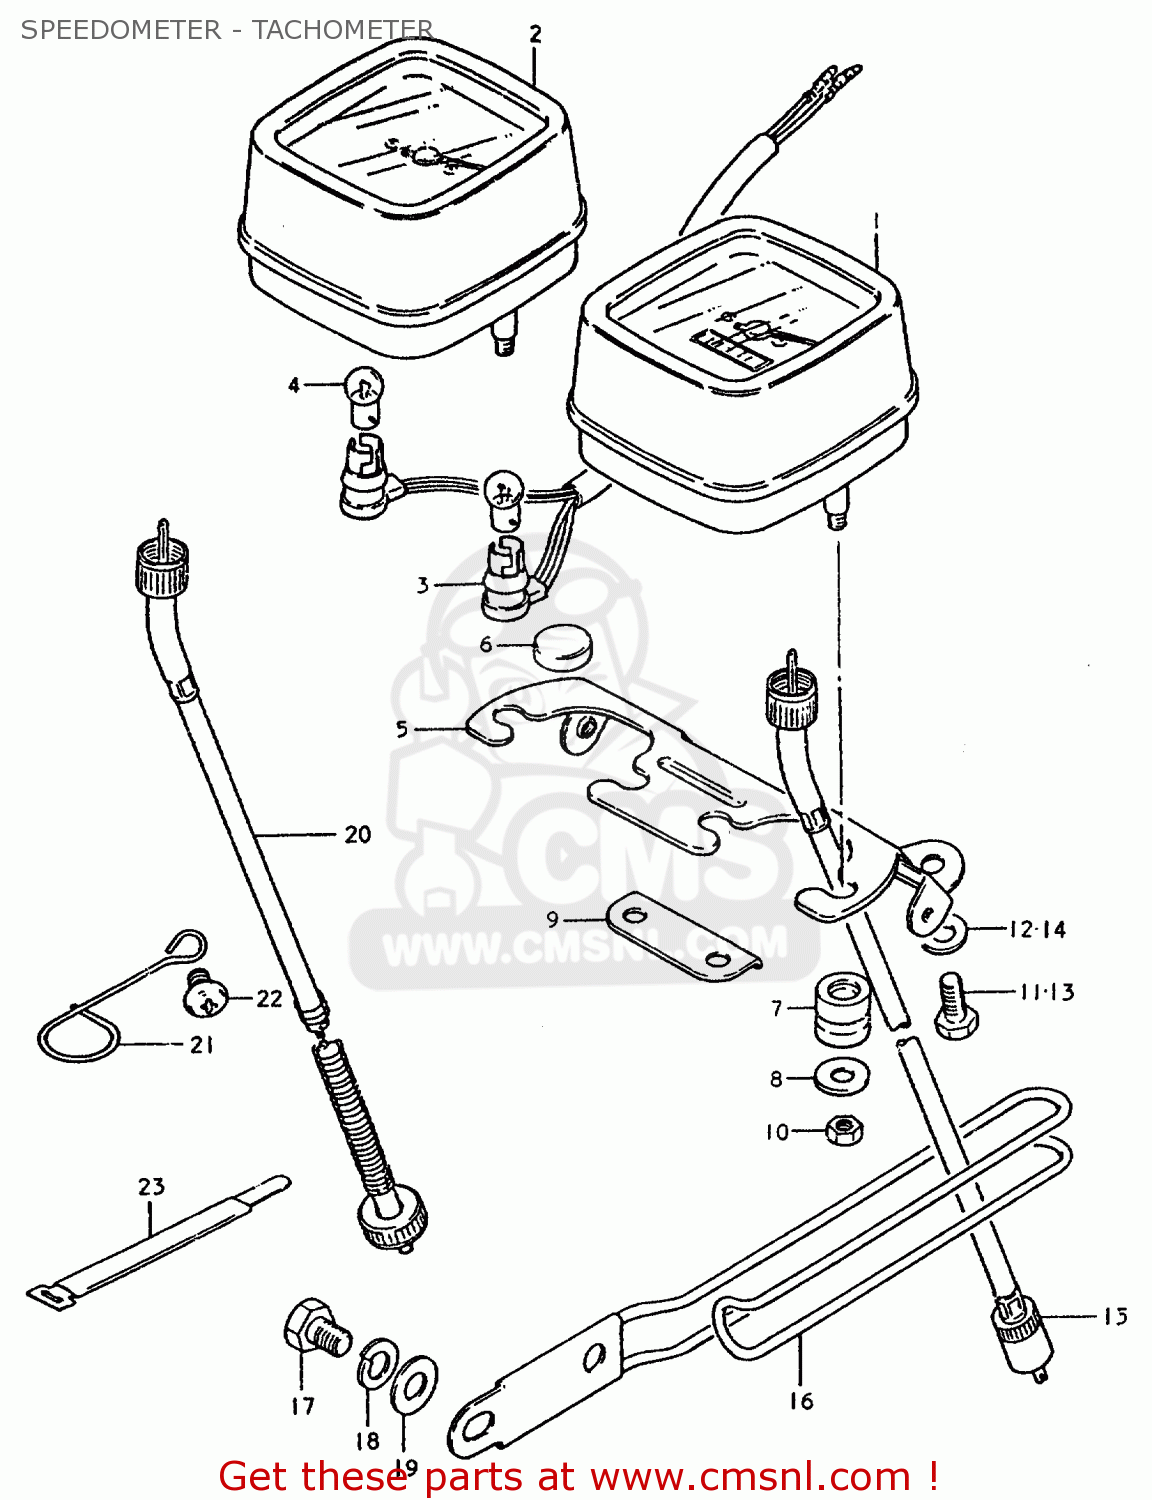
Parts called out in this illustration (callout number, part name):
1	SPEEDOMETER
2	TACHOMETER
3	SOCKET,METER
4	BULB(6V1.7W,STANLEY,A61A)
5	BRACKET
6	CUSHION,METER
7	CUSHION
8	WASHER,METER
9	PLATE,METER CONNECTING
10	NUT
11	BOLT 8X12
12	WASHER
13	BOLT, UPPER
14	WASHER
15	CABLE, SPEEDOMETER
16	GUIDE,CABLE
17	BOLT 8X12
18	LOCK WASHER
19	WASHER
20	CABLE, TACHOMETER
21	CLIP
22	BOLT
23	CLAMP
